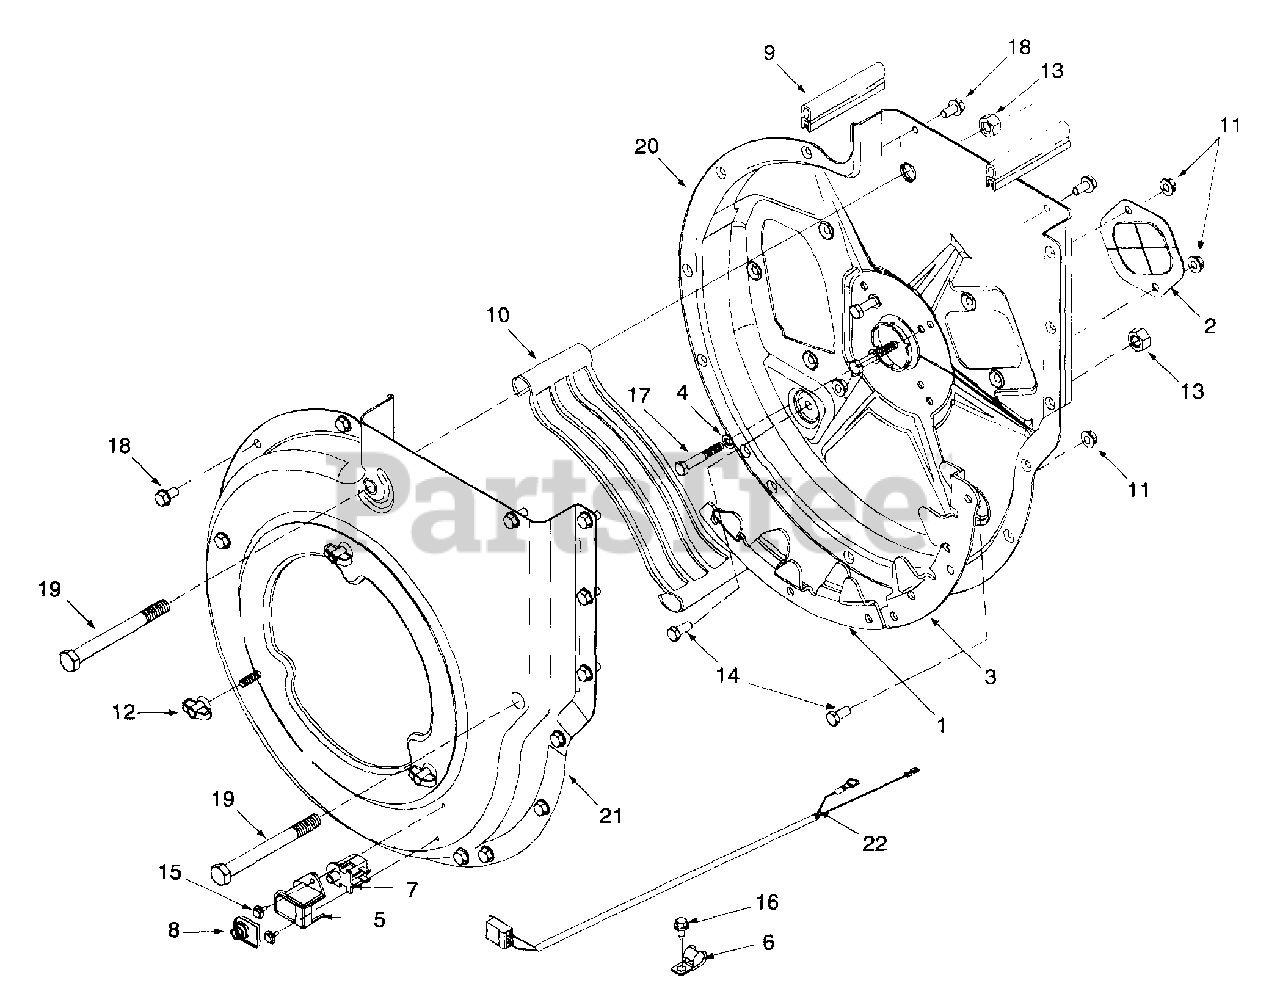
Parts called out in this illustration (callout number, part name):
4	Washer, Lock, 5/16
5	Cover, Safety Switch Mtg.
6	Clamp
7	Switch, Snap Mount
8	Cover, Switch
9	Rubber Seal
10	Screen, Discharge
11	Nut, Hex Flange Lock, 5/16-18
12	Knob, 5/16-18
13	Nut, Hex Center Lock, 1/2-13
14	Screw, Hex Cap, 5/16-18 x .75
15	Screw, Wash Hd Tapp #10-16
16	Screw, Wash Hd Tapp 1/4-14
17	Screw, Hex Cap, 5/16-18 x 2
18	Screw, Wash Hd Tapp 5/16-18
19	Screw, Hex Cap, 1/2-13 x 5.0
22	Harness, Wire
